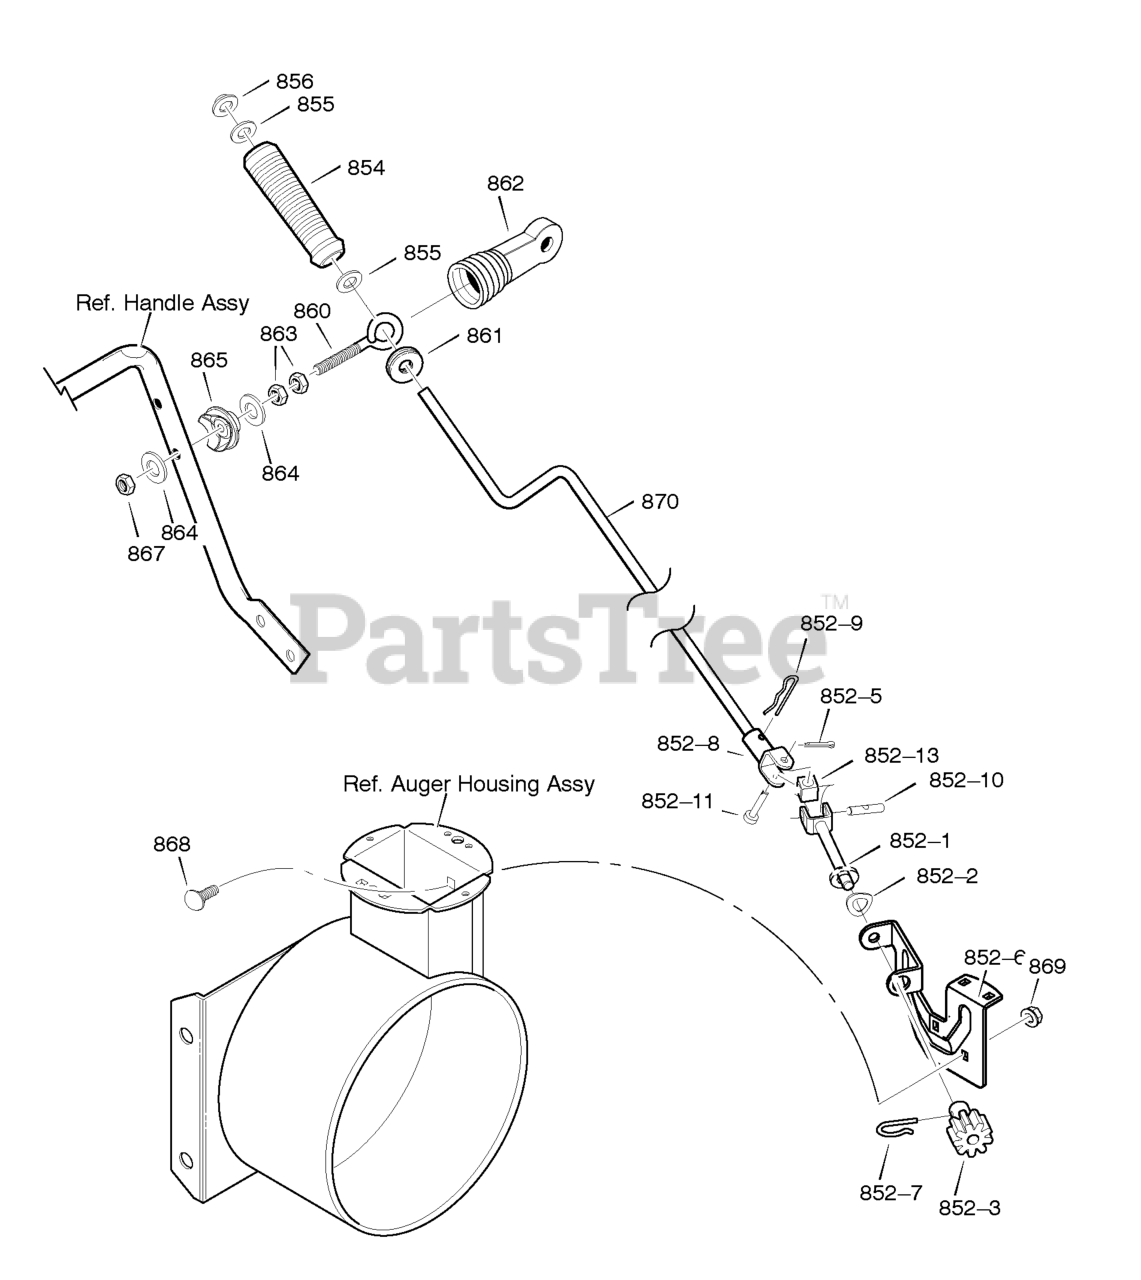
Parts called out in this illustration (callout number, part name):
852-1	ASSEMBLY, YOKE & ROD
852-2	WASHER, CURVED SPRING
852-3	GEAR, CHUTE ROTATION 9T
852-5	PIN, COTTER
852-6	BRACKET, GEAR MOUNT
852-7	PIN, HAIR
852-8	ASSEMBLY, YOKE ADAPTER YZ
852-9	PIN, HAIR
852-10	PIN, UNIVERSAL JOINT
852-11	PIN, CLEVIS
852-13	HOUSING, UNIVERSAL
854	KNOB, SLEEVE
855	FLATWASHER
856	NUT, PUSH ON 3/8"
860	EYE BOLT 3/8-16X6.00
861	GROMMET, EYE BOLT
862	BOOT, EYE BOLT
863	NUT, 3/8-16 HEXJAM
864	FLATWASHER .406X.81X.066
865	ADAPTER, BOOT
867	NUT, 3/8-16 HEXNYL
868	BOLT, CARRIAGE 1/4-20 X 1.00
869	NUT, 1/4-20
870	CRANK, ASSY CHUTE
